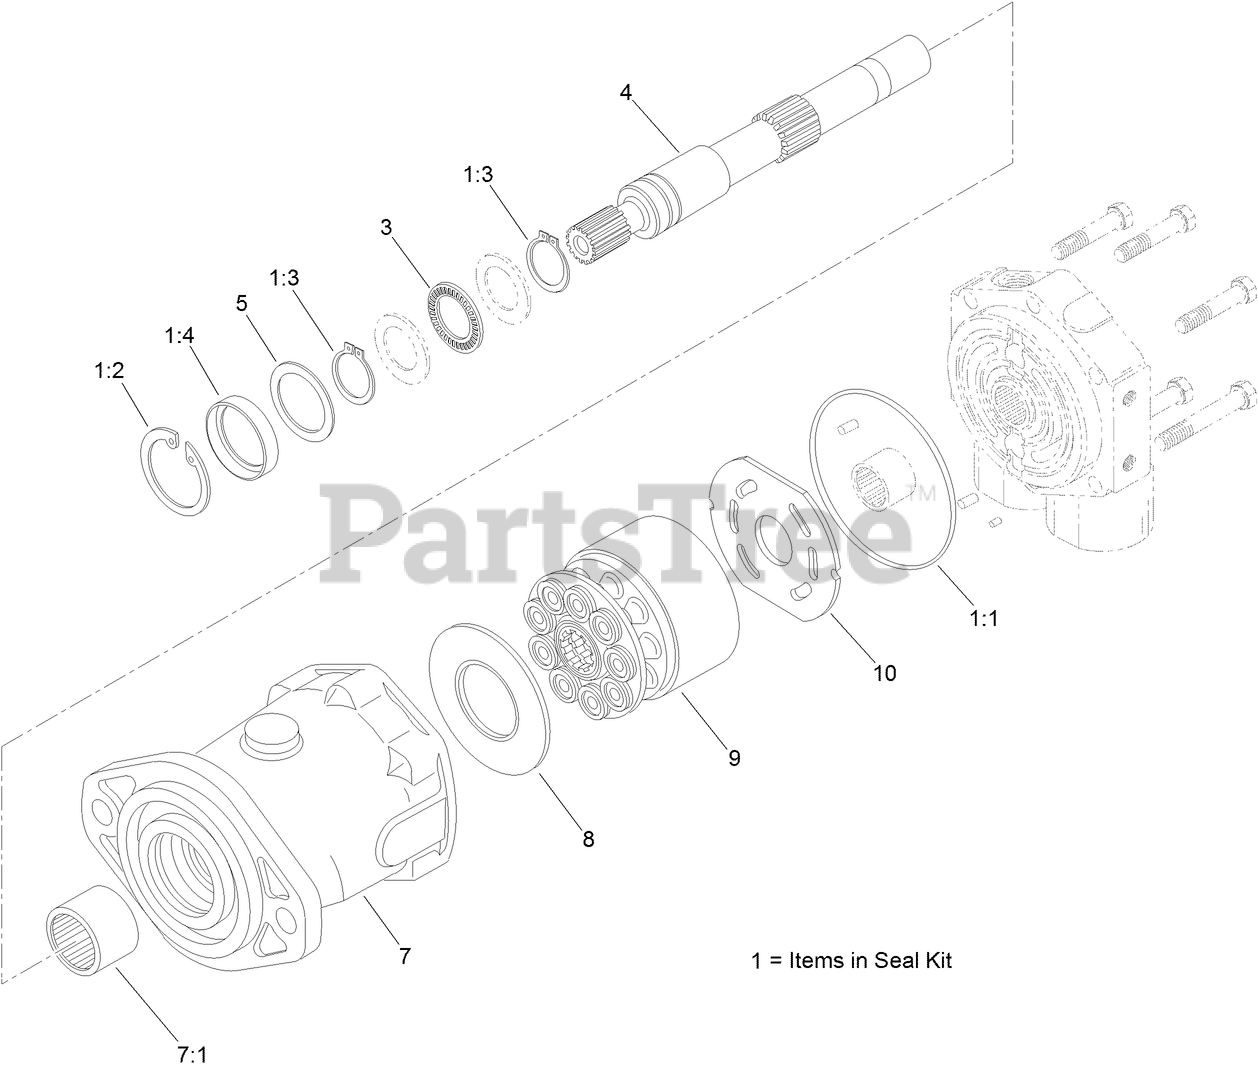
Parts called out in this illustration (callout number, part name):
1	Seal Kit
1:1	O-RING
1:2	RING-RETAINING
1:3	RING-RETAINING
1:4	SEAL-SHAFT
3	BEARING-THRUST
4	SHAFT-DRIVE
5	WASHER
7	HOUSING ASM
7:1	BEARING-NEEDLE
8	INSERT-PLATE, CAM
9	ROTATING KIT
10	PLATE-VALVE
